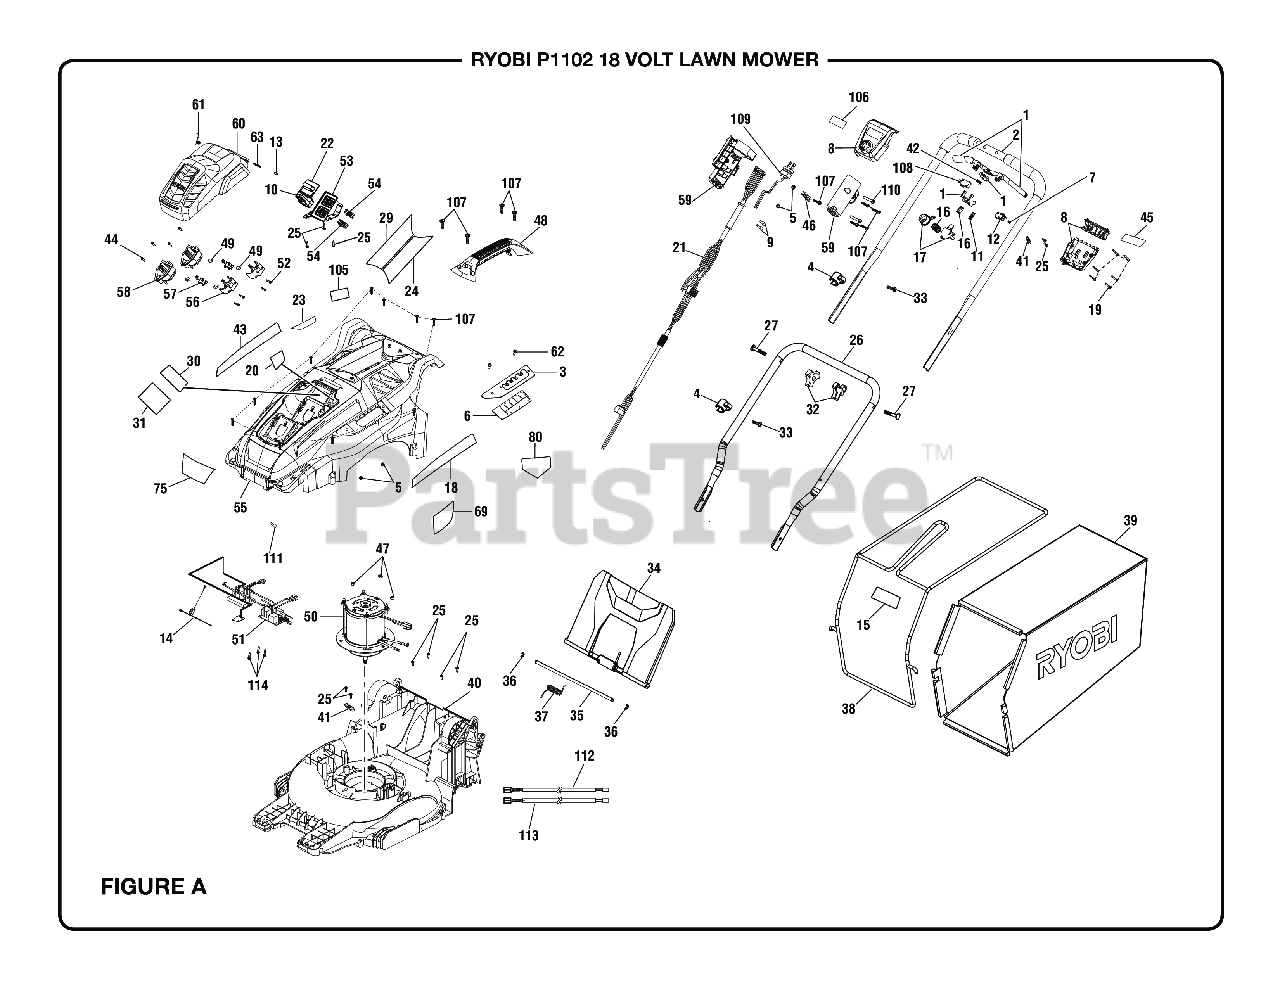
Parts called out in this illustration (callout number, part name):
1	Trigger Handle Assembly
2	Upper Handle Assembly
3	Height Adjustment Plate
4	Cord Clamp
5	Lock Nut (M5 x 0.8 mm)
6	Dust Gasket
7	Screw (M4 x 10 mm, T20 Torx Pan Hd.)
8	Trigger Housing Assembly
9	Wire Connector (Closed End)
10	Start Key
11	Compression Spring (Trigger)
13	Battery Door Axle
14	Lead Wire w/Terminal Block
15	Starting Instructions Label
16	Handle Adjustment Spring
17	Start Button Assembly
18	Lithium Label (Left)
19	Screw (M4-18 x 30 mm, T15 Torx Soc. Hd.)
20	Fuel Gauge Label
21	Starter Cable (Long)
22	Slide Door
23	Icon Warning Label
24	Warning Icon Label (Right)
25	Screw (M4 x 16 mm, T20 Torx Pan Hd.).
26	Lower Handle
27	Screw (M8 x 57 mm)
29	Warning Icon Label (Right)
30	Start Key Label (Eng)
31	Start Key Label (FR/SP)
32	Knob (526906001)
33	Screw (M3 x 20 mm, Pan Hd.)
34	Rear Discharge Door
35	Rear Door Axle
36	Retaining Ring (E)
37	Torsion Spring (Rear Door)
38	Bag Frame
39	Bag
41	Wire Press Plate
42	Compression Spring (Trigger Handle)
43	Lithium Label (Right)
44	Screw (M4 x 16 mm, T15 Torx Pan Hd.)
45	Starting Instructions Label
46	Cord Clip
47	Lock Nut (M6)
49	Rubber Cushion
51	Start Circuit Board
52	Screw (M4 x 16 mm, T20 Torx Socket Pan Hd.)
53	Key Holder Assembly
54	Female Terminal
55	Deck Cover
56	Press Cover (Battery Connect)
57	Plate (Battery Connect)
58	Base (Battery Connect)
59	AC Plug Housing Assembly
60	Battery Cover
61	Torsion Spring (Battery Door)
62	SCREW (M5 x 16 mm SOC. WASHER HD. CAP)
63	Compression Spring
69	Height Adjust Label
75	Ryobi Logo Label (Handle)
80	Danger Label (No Hands/Feet)
105	Data Label
106	Ryobi Logo Label (Handle)
107	Screw (M4 x 20 mm, T20 Torx Pan Hd. S.T.)
108	Micro Switch
109	Plug Wire
110	Screw (M5 x 30, T20 Torx Pan Hd.)
111	Wire Connector (Closed End)
112	Lead Wire (Red)
113	Lead Wire (Brown)
114	Screw (M3 x 8 mm, Pan Hd., Pan Hd)
